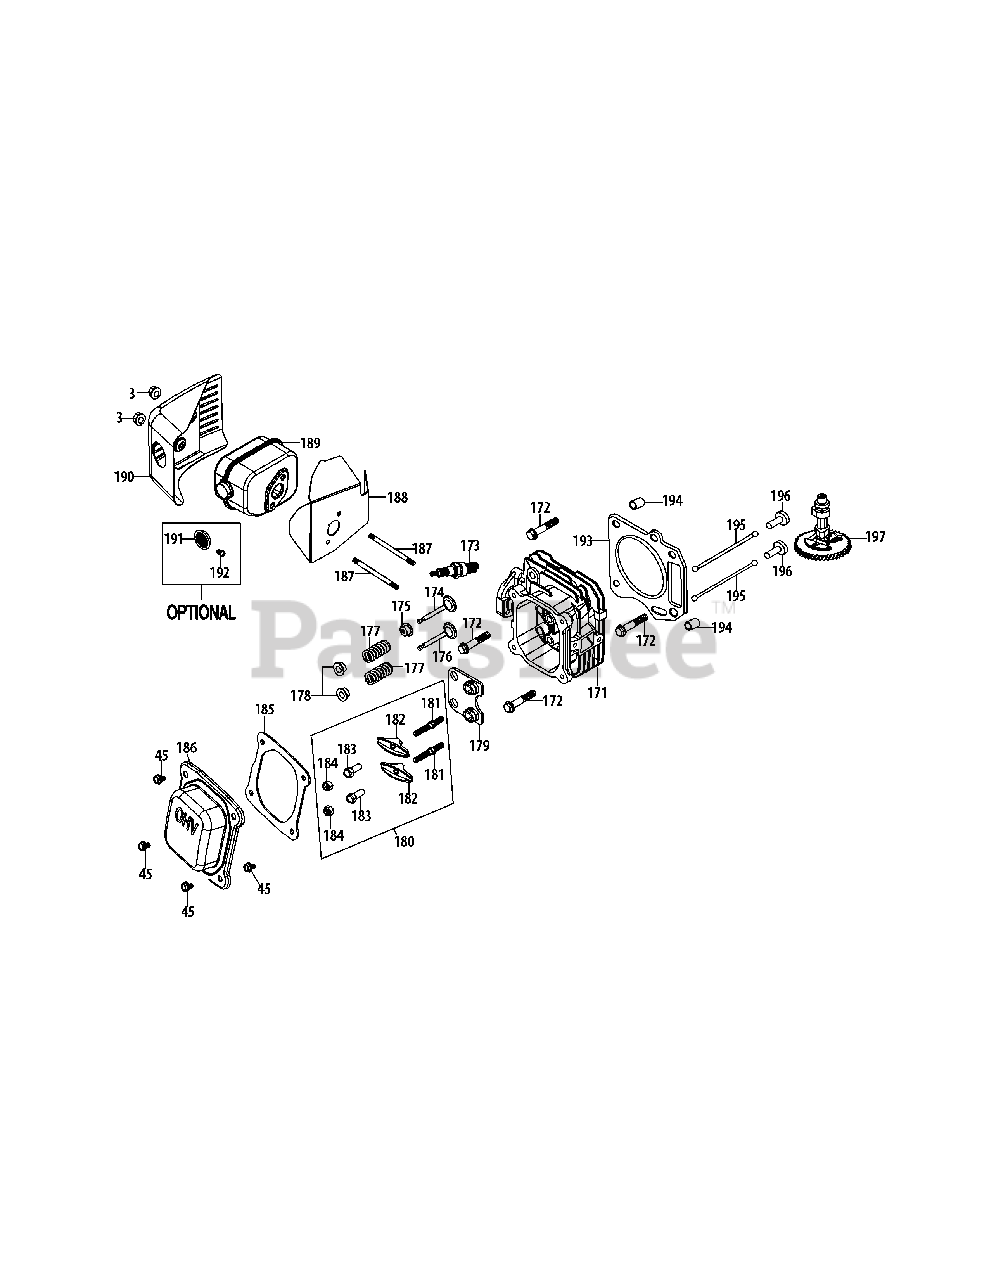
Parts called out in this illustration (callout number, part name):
3	Nut M6 X 10 Mm
45	Bolt M6×14
171	Cylinder Head Assembly
172	Head Bolt M8×54
173	Spark Plug/F6Rtc
175	Intake Valve Seal
177	Valve Spring
178	Valve Spring Retainer
179	Push Rod Guide
180	Rocker Arm Assembly
181	Rocker Arm Stud
182	Rocker Arm
183	Fulcrum Nut
185	Valve Cover Gasket
186	Valve Cover
187	Muffler Stud M6x95
187	Muffler Stud Assemlby
188	Muffler Gasket
189	Muffler Assembly
190	Muffler Shield
191	Spark Arrestor
192	Spark Arrestor Screw
193	Cylinder Head Gasket
194	Cylinder Head Dowel 10x16
195	Push Rod Kit
197	Camshaft Assembly
